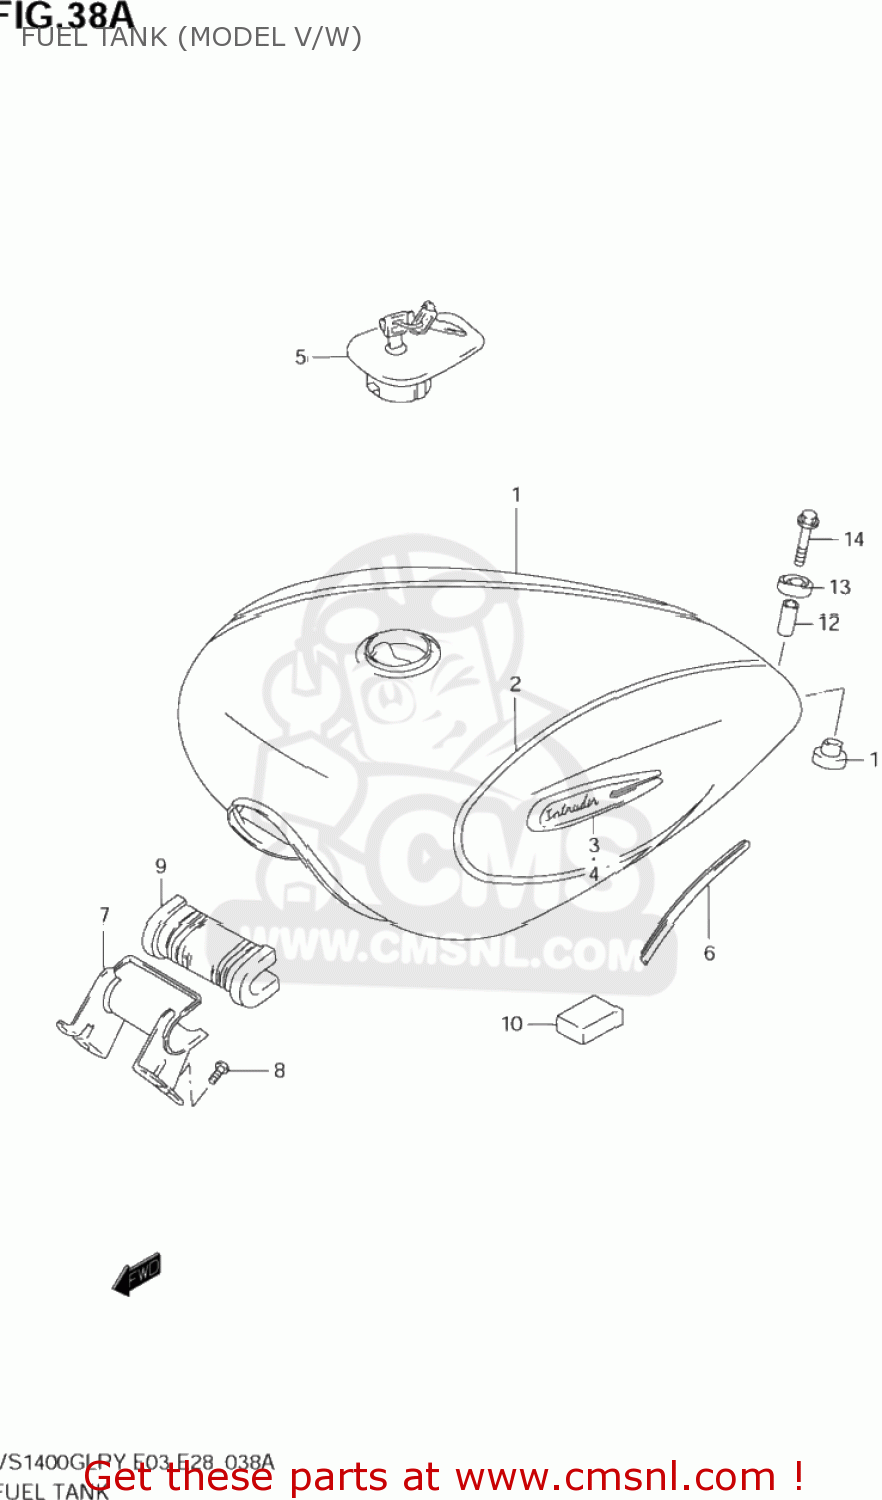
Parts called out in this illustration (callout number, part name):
1	TANK ASSEMBLY,FUEL
2	TAPE SET,FUEL TANK
3	EMBLEM,FUEL TANK,R
4	EMBLEM,FUEL TANK,L
5	CAP SET,FUEL TANK
6	MOLDING
7	BRACKET,TANK
8	SCREW
9	CUSHION,FUEL TANK FR
10	CUSHION
11	CUSHION
12	SPACER(6.5X9X22.5)
13	CUSHION
14	BOLT
.2	TAPE SET,FUEL TANK
